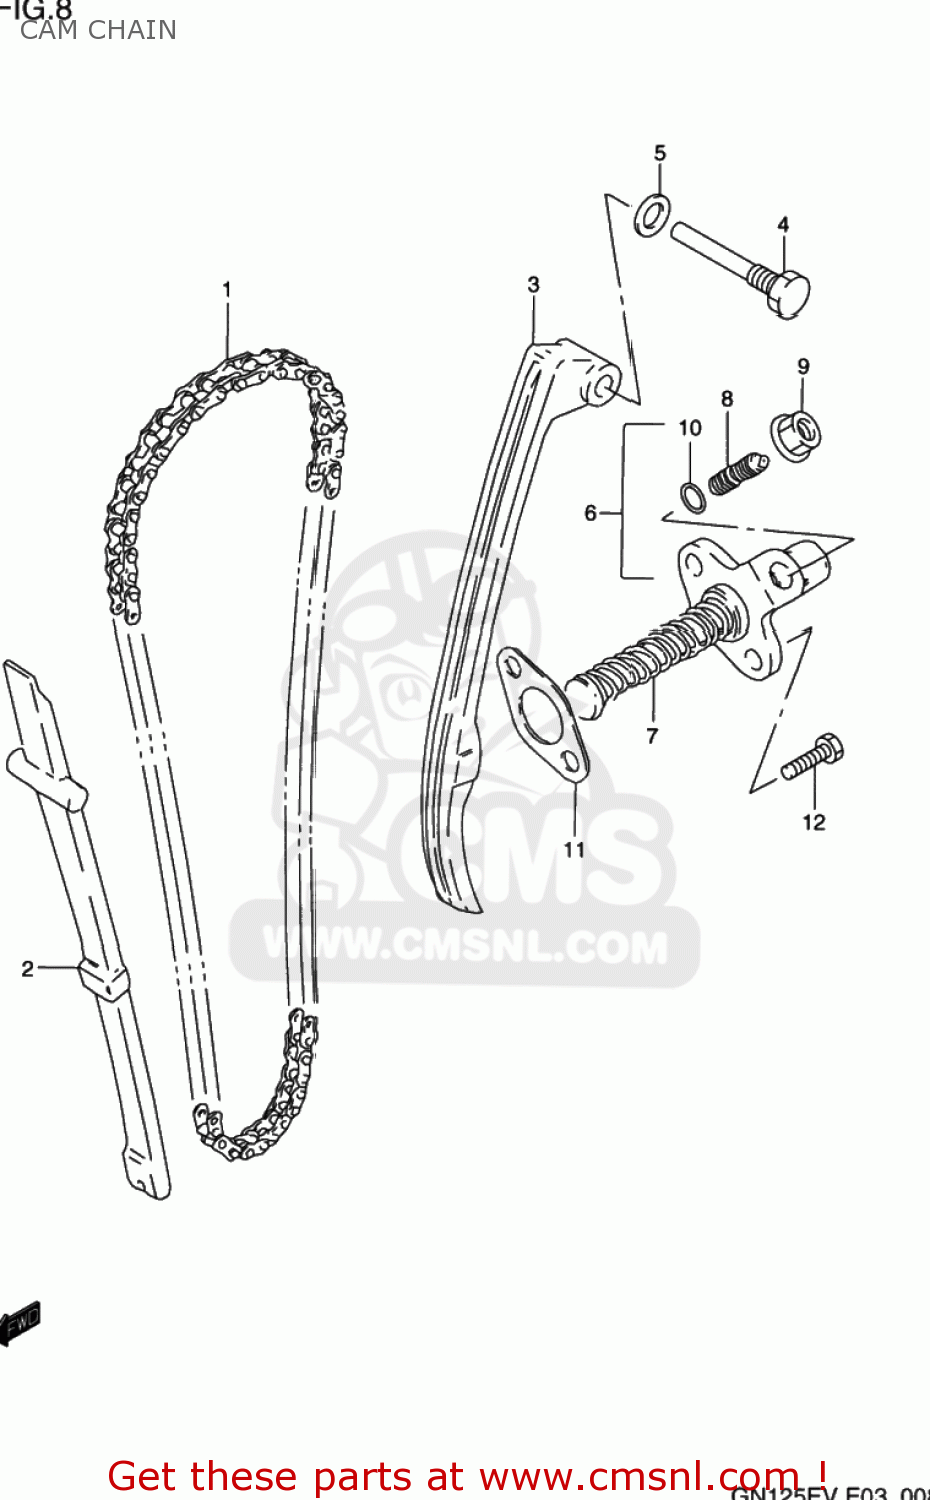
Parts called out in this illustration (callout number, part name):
1	CHAIN,CAMSHAFT DRIVE
2	GUIDE,CAM CHAIN
3	TENSIONER,CAM CHAIN
4	BOLT,CAM CHAIN TENSIONER
5	GASKET 8.2X14X1 (NAS)
6	ADJUSTER ASSY,TENSIONER
7	SPRING
8	SCREW
9	NUT
10	O RING(D:1.9,ID:5.7)
11	GASKET,TENSIONER ADJUSTER (NAS)
12	BOLT
